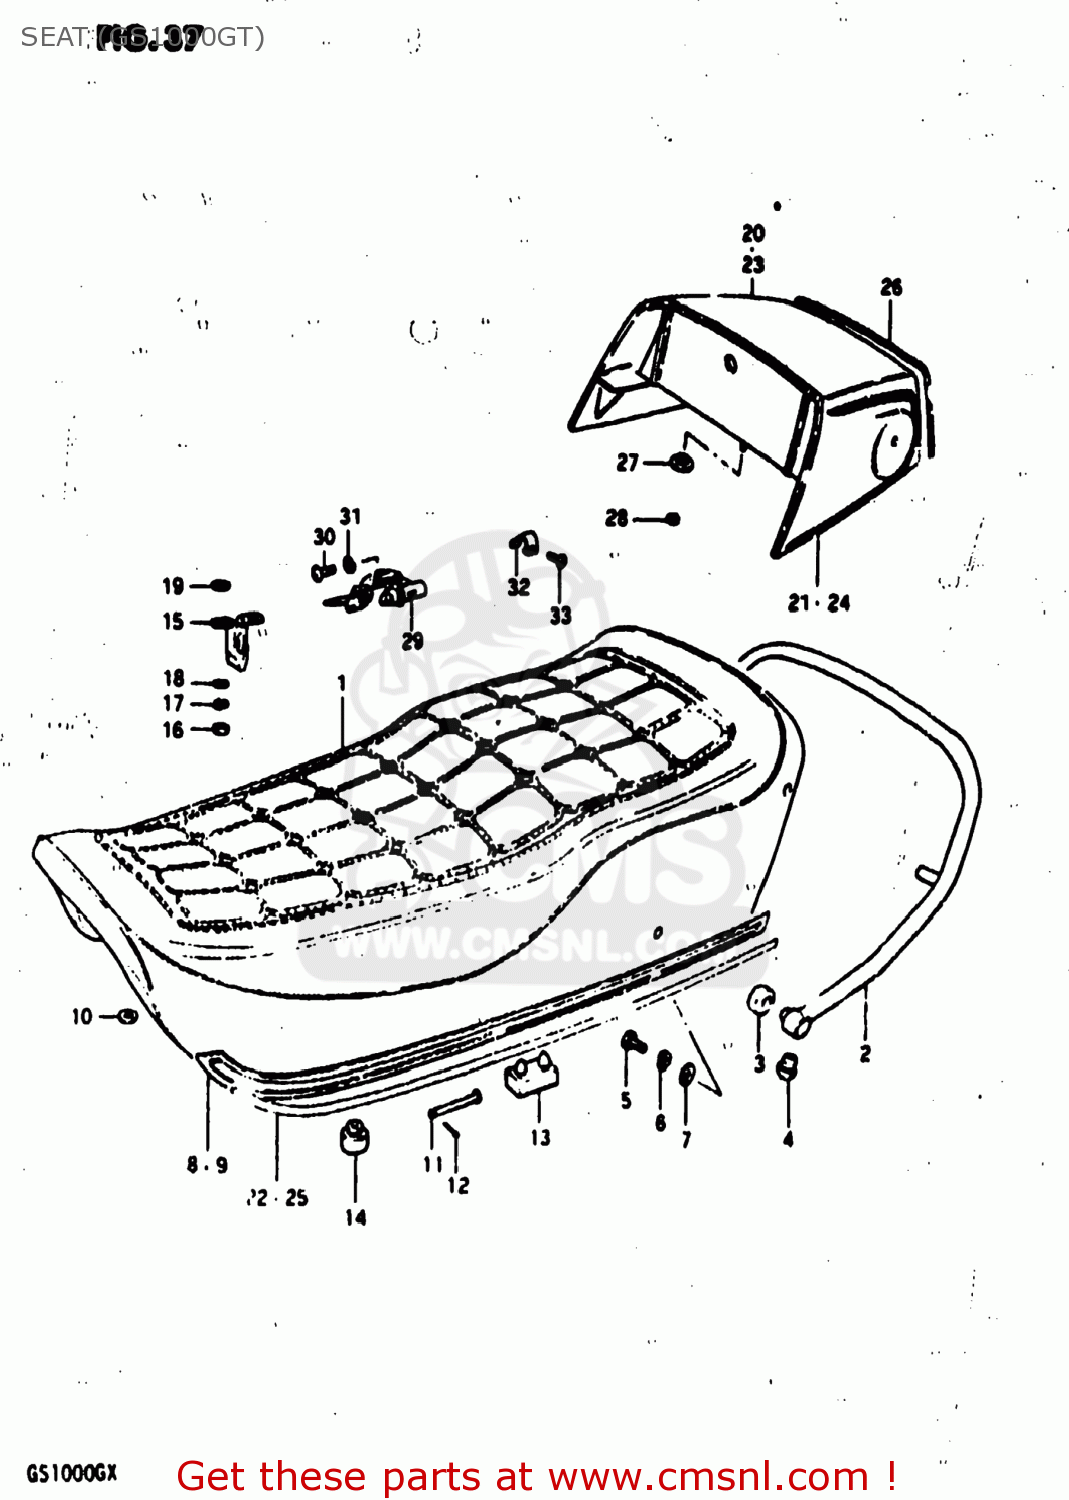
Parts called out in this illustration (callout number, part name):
1	SEAT ASSEMBLY
2	HANDLE,PILLION RIDER
3	CUSHION
4	END,SHEET HANDLE
5	BOLT
6	LOCK WASHER
7	WASHER
8	MOLE,R
9	MOLE,L
10	NUT
11	PIN
12	PIN
13	CUSHION
14	CUSHION
15	STRIKER,SEAT LOCK
16	NUT
17	LOCK WASHER
18	WASHER 6MM
19	WASHER (6.5X20X1.2)
20	BOX SET,SEAT TAIL
21	TAPE SET,SEAT TAIL COVER
22	TAPE SET
23	BOX SET,SEAT TAIL
24	TAPE SET,FUEL TANK
25	TAPE SET
26	MOLDING,SEAT TAIL COVER
27	WASHER
28	NUT 6MM
29	LOCK ASSY,SEAT
30	SCREW
31	LOCK WASHER
32	SPRING,HELMET HOLDER
33	SCREW
